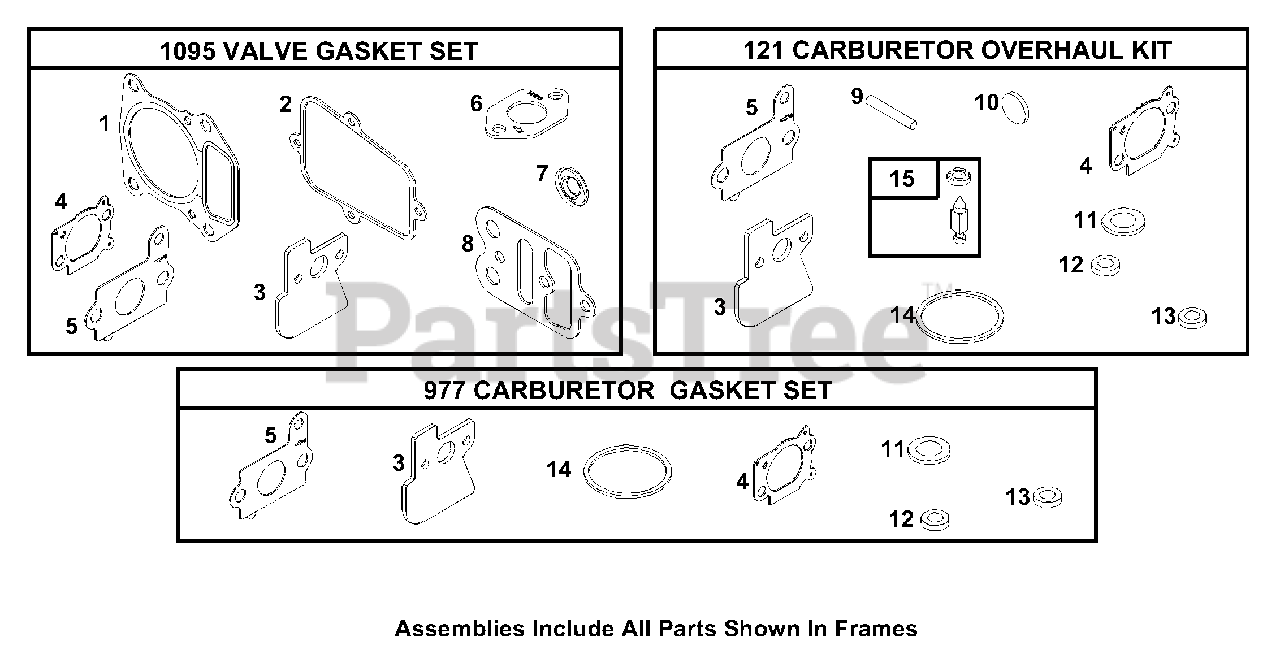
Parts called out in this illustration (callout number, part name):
1	Gasket-Cylinder Hd.
2	Gasket (Rocker Cover)
3	Spacer-Carburetor
4	Gasket-Air Cleaner
5	Gasket-Intake
6	Gasket-Exhaust
7	Seal-Valve
8	Gasket-Cylinder Head Plate
9	Pin-Float Hinge
10	Welch Plug
11	Washer-Sealing
12	Seal-Choke Shaft
13	Seal-Dust (Throttle Shaft)
14	Gasket-Float Bowl
15	Kit-Needle/seat
121	Carburetor Overhaul Kit
977	Carburetor Gasket Set
1095	Valve Gasket Set
